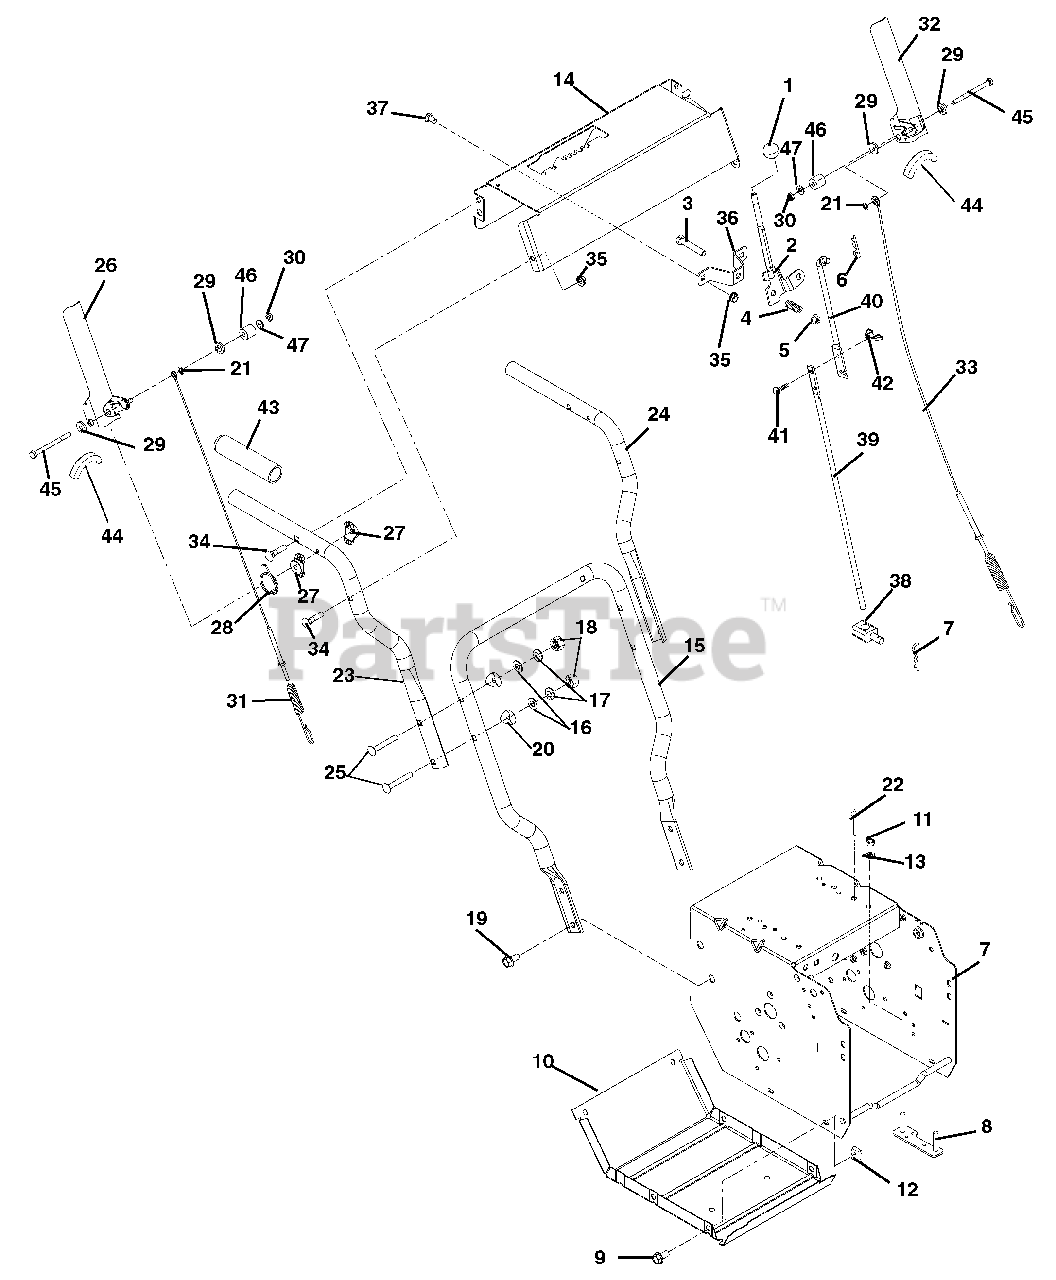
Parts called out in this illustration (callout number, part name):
1	KNOB,BALL -BLACK 1.47" .375-16
2	WMT, SHIFT LEVER
3	@BLT-HEX .38-16X2.00 GR5 YWZC
4	SG-COMP .125X.781X1.250
5	@NUT-LK-TOP-FLG .38-16 YWZC
6	PIN-HAIR INT .08X.18X1.18 YWZC
7	WELDMENT, FRAME
8	STRAP, ENGINE BOLT-WELDMENT
9	BLT-HEX .25-20X.75 HWH YZ GR5
10	COVER, BOTTOM
11	@NUT-HEX .31-18 YWZC
12	NUT-RTNR .25-20X.56
13	WSHR-LK .312X.097 HVY YWZC
14	CONTROL PANEL W/DECAL - BRUSH
15	HANDLEBAR, LOWER - COMPACT
16	@WSHR-FL-STL.38X.875X.083 YWZC
17	@WSHR-LK .31X.078 REG YWZC
18	@NUT-LK-NYL .312-18 YWZC
19	BLT-SERHFWH .38-16X.75 YWZC
20	SPACER, HANDLEBAR
21	RG-RTNG-EXT .250X.010
22	RVT-POP .187 YZ
23	HANDLEBAR, UPPER-RH 920 BRUSH
24	HANDLEBAR, UPPER - LH COMP/DEL
25	@BLT-RDHDSQNK .31-18X2.25 G5YZ
26	PADDLE, CLUTCH - RH COMPACT
27	SPACER, HANDLEBAR
28	SPRING, TORSION
29	BSHG, FLG .266X.42X.150 PM
30	NUT-JAM-NYL .250-20 W/INSERTYZ
31	CABLE, ATTACHMENT, COMPACT
32	PADDLE, CLUTCH - LH COMPACT
33	CABLE, TRACTION - COMPACT
34	BLT-RDHDXLSQNK .31-18X1.5 G5YZ
35	@NUT-LK-TOP-FLG .31-18 YWZC
36	BRACKET, SHIFT MOUNT
37	@BLT-RHDSSQNK .31-18X.62 G5YZ
38	PIVOT,SHIFT ROD .375-16(TRUNN)
39	ROD, SHIFT - LOWER
40	ROD, SHIFT - UPPER
41	@BLT-RDHDSQNK .25-20X.75 G5YZ
42	@NUT-LK-TOP-FLG .25-20 YWZC
43	HANDLE GRIP
44	EDGING, CLUTCH PADDLE - 2.00"
45	@BLT-HEX .25-20X3.25 YWZC
46	BSHG, SLV .266 X .750 X .750
47	@WSHR-FL-STL.281X.62X.065 YWZC
